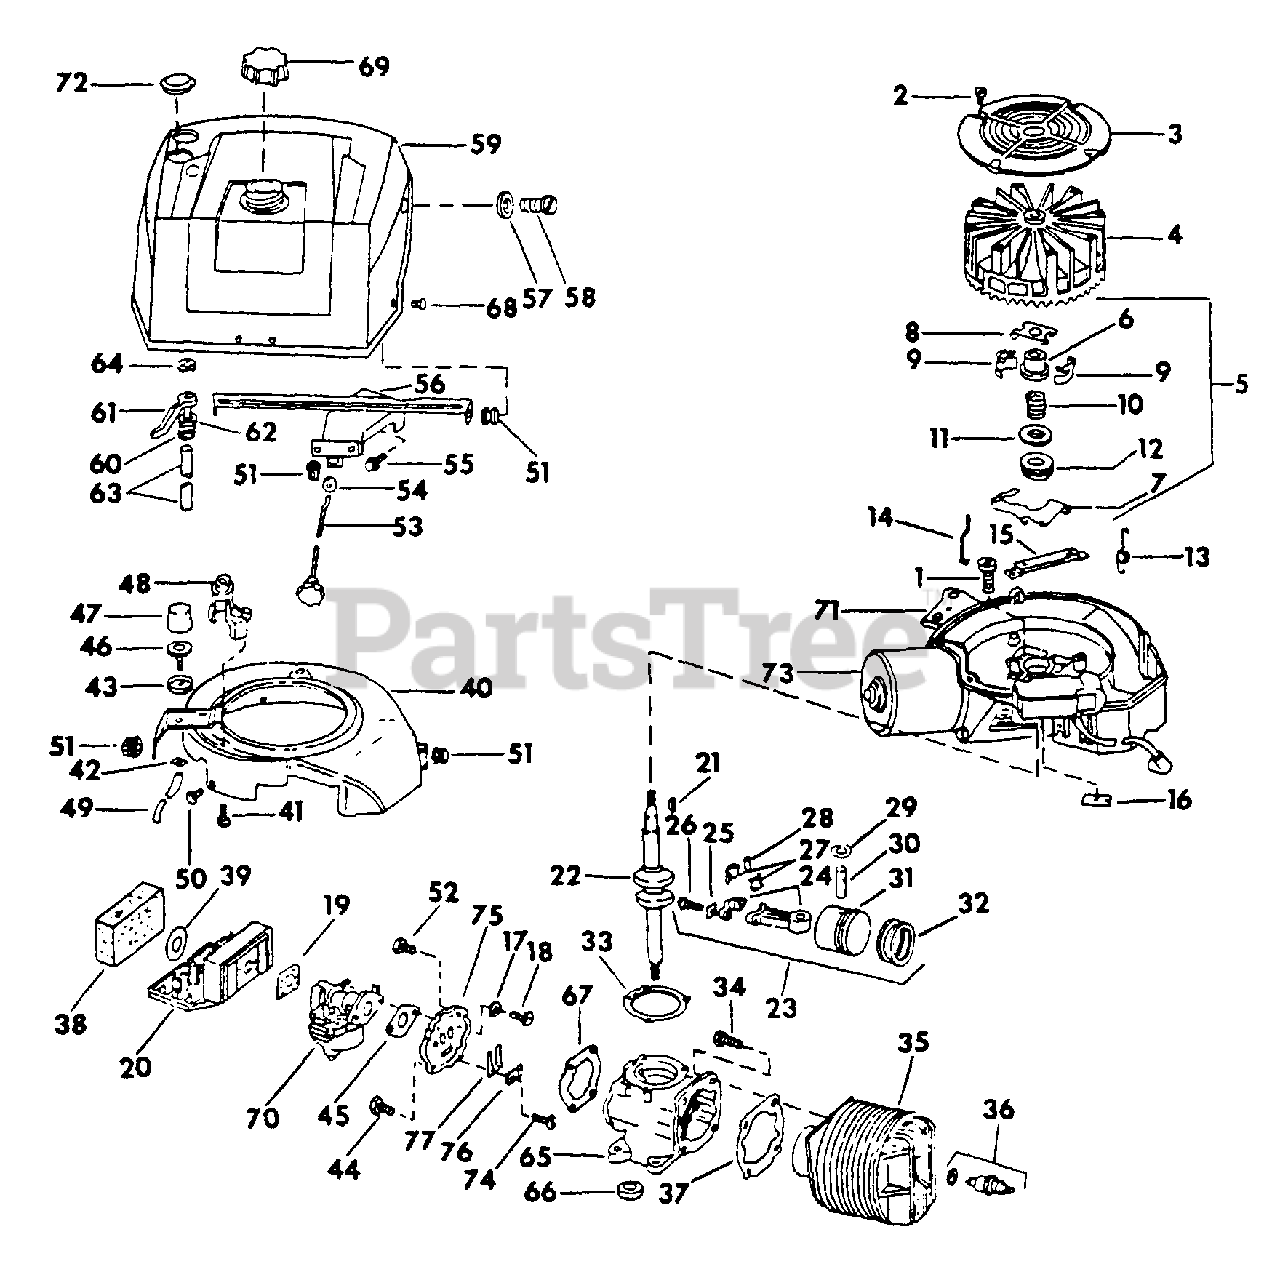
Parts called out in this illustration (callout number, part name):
1	SCREW, 5/16-18 X 1-1/4 ZND HEX-HD CAP
2	SCREW, 10-24 X 1/2 TRUSS-HD REC TAP.
3	SCREEN, FLYWHEEL
5	GOVERNOR ASSY
6	COLLAR, GOVERNOR
7	LEVER, GOVERNOR
8	YOKE, GOVERNOR
9	WEIGHT, GOVERNOR
10	SPRING, GOVERNOR
11	WASHER, THRUST
12	COLLAR, THRUST
13	SPRING, VARIABLE SPEED
14	ROD, GOVERNOR
15	BRACKET, GOVERNOR LEVER
20	CASE, AIR FILTER
21	KEY, CRANKSHAFT
23	PISTON & CONNECTING ROD ASSY
24	ROD ASSY, CONNECTING
25	LOCKPLATE, SCREW
26	SCREW, CONNECTING ROD
27	LINER, CONNECTING ROD
28	BEARING SET, NEEDLE
29	RING, RETAINING
32	RING SET, PISTON - 2 RINGS
33	GASKET, CRANKCASE TO ARM PLATE .010
34	SCREW, CYL TO CRANKCASE
36	SPARK PLUG & GASKET
37	GASKET, CYL TO CRANKCASE
38	ELEMENT, FILTER
40	BAFFLE ASSY, AIR
44	SCREW, HH REED PLATE TO CRANKCASE
45	GASKET, CARBURETOR
48	BRACKET & EYELET
51	GROMMET, COVER MTG
52	SCREW, HH REED PLATE TO CRANKCASE
56	BRACKET, SHROUD
59	SHROUD, TANK & VALVE ASSY
60	CLIP, SPRING
65	CRANKCASE AND SEAL ASSY
67	GASKET, REED PLATE
68	SCREW, COVER MTG
70	CARBURETOR ASSY
71	MAGNETO ASSY
73	STARTER ASSY, ELECTRIC
75	REED PLATE ASSY
76	PLATE, BACKUP
